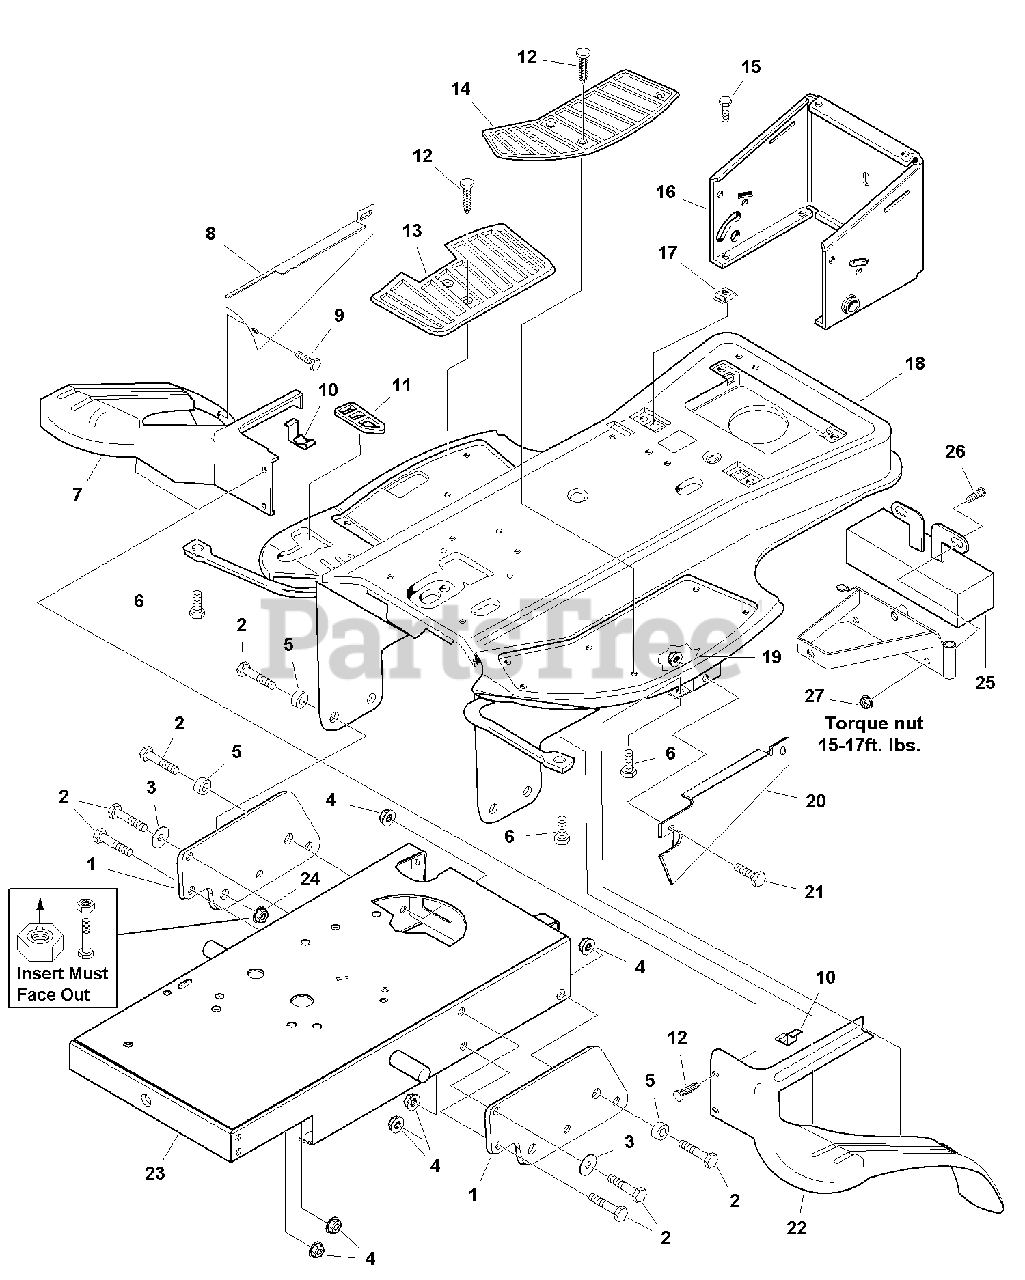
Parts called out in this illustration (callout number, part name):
1	PLATE, Pivot
2	CAPSCREW, Hex Head, 3/8-16 x 1-1/4, Black
3	WASHER, 3/8, Black
4	NUT, Hex Flange Lock, Black
6	CAPSCREW, Hex Head, Flange Lock, 5/16-18 x 1/2, Black
7	SHROUD, Wheel, RH
8	SKIRT, Side, RH
9	CAPSCREW, Hex Washer Head, Plastite, # 10-14 x 5/8, Black
10	CLIP, Shroud
12	FASTENER, Panel
13	PAD, Footrest, RH
14	PAD, Footrest, LH
15	CAPSCREW, Hex Head Whiz Lock, 5/16-18 x 3/4, Black
16	WRAPPER, Rear Frame
17	NUT, Speed, Lug, 5/16-18
18	FRAME ASSEMBLY, Rear
19	NUT, Hex, Flange, 1/4-20, Black
20	SKIRT, Side, LH
21	CAPSCREW, Hex Head, 1/4-20 x 7/8, Black
22	SHROUD, Wheel, LH
23	FRAME ASEMBLY, Transmission
24	NUT, Hex Lock Aluminum Insert, 3/8-16
25	WEIGHT & TAB ASSEMBLY, 75 lbs.
26	CARRIAGE BOLT, 5/16-18 x 1
27	NUT, Hex, Flange Whiz Lock, 5/16-18
